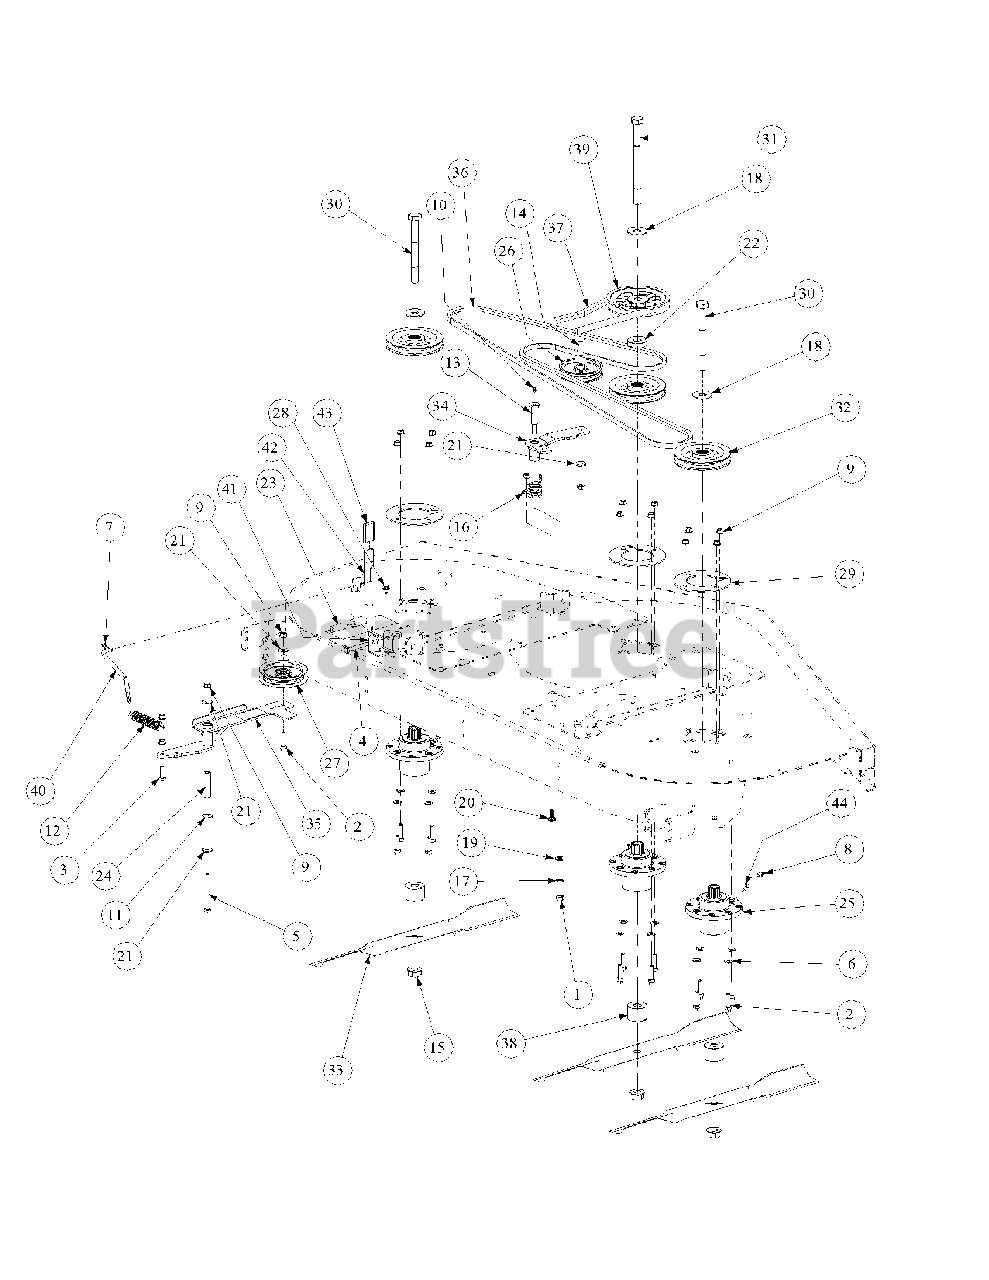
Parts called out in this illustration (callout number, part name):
1	Hex Nut, 7/16-14
2	Hex Cap Screw, 3/8-16 x 1-1/2
3	Hex Cap Screw, 3/8-16 x 1-1/4
4	Hex Cap Screw, 3/8-16 x 2-1/2
5	Hex Cap Screw, 3/8-16, 4.00
6	Flat Washer, 3/8
7	Cotter Pin, .072 x 1.12 Long
8	Taper Grease Fitting, 1/4-28, 45 degree
9	Flange Lock Hex Nut, 3/8-16
10	Grease Fitting, 1/4-28 x 3/16
11	Idler Washer
12	Extension Spring, 1.0 x OD x 5.00
13	Shoulder Screw, 7/16-14
14	Hex Carriage Screw, 3/8-16, 1.75
15	Flange Hex Nut, 3/4-16
16	Torsion Idler Spring
17	Lock Washer, 7/16
18	Flat Washer, .781 ID 2.00 OD, .105
19	Flat Washer, .469 ID, .875 OD, .105
20	Carriage Bolt, 3/8-16 x 1
21	Flat Washer, .406 ID, 1.0 OD, .105
22	Spacer, .76 ID x 2.0 OD x .477
23	Spacer, .39 ID x .63 OD x 1.75
24	Spacer, .39 ID x .625 OD x 2.75
25	Aluminum Spindle Assembly
26	Flat Pulley
27	Idler Pulley, 4.06 OD
28	Screw, TT, 3/8-16 x .50,
29	Aluminum Spindle Support Plate
30	Hex Cap Screw, 3/4-16, 7.50
31	Hex Cap Screw, 3/4-16, 9.00
32	V-Pulley, 5.75 OD
33	Bahia Blade, 25.0, .756 ID
34	Idler Arm Assembly, Deck
34	Bearing Sleeve
35	Idler Arm Assembly, Drive
35	Bearing Sleeve
36	V-Belt, B Section x 124.0 LG
37	V-Belt, B Section x 99.25 LG
38	Spacer, .760 ID x 2.00 OD x .330
39	V-Pulley, 6.360 OD x .750 Bore, Cast
40	Spring Tension Rod
41	Tension Idler U-Bracket
42	Handle Tension Weldment
43	Tension Idler Handle Grip
44	Straight Adapter Fitting
